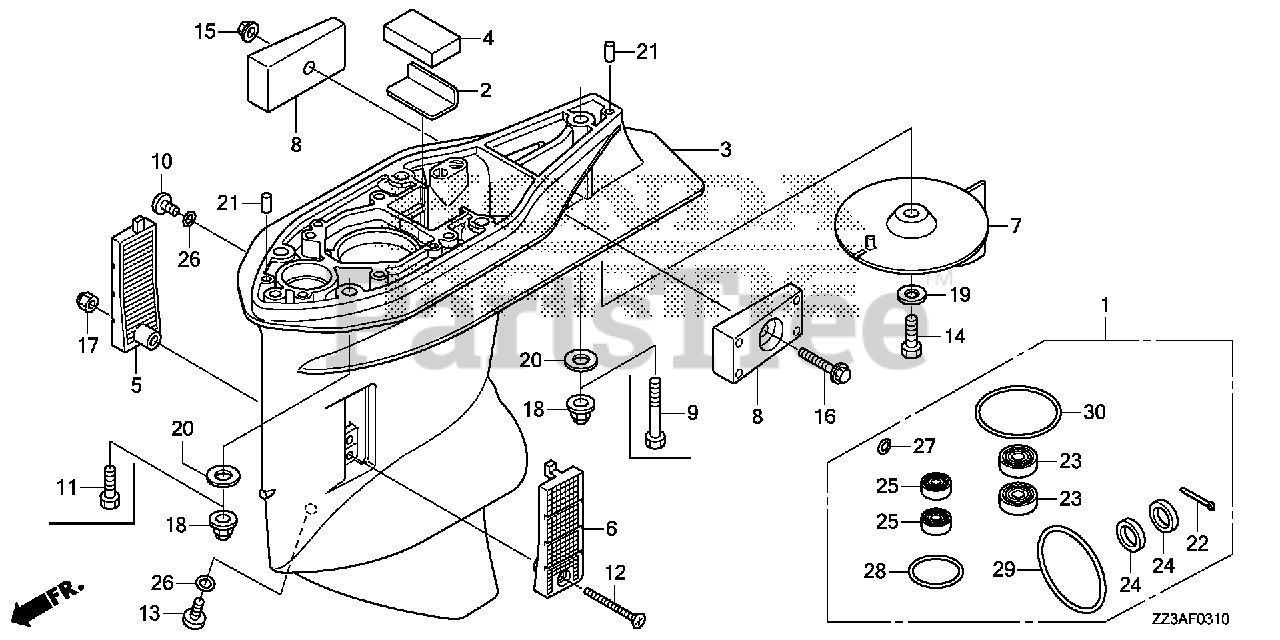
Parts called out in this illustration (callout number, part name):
1	CASE KIT, GEAR
2	PLATE, RUBBER SETTING
3	CASE, GEAR *NHB14M* (AQUA MARINE SILVER METALLIC)
4	GROMMET, GEAR CASE
5	SCREEN, R. WATER
6	SCREEN, L. WATER
7	TAB, TRIM *NHB14M* (AQUA MARINE SILVER METALLIC)
8	METAL, ANODE
10	BOLT, OIL CHECK
12	SCREW, FLAT (5X37)
13	BOLT, DRAIN PLUG
14	BOLT, HEX. (8X20)
15	NUT, SELF-LOCK (6MM)
16	BOLT, FLANGE (6X30)
17	NUT, SELF-LOCK (5MM)
18	NUT, SELF-LOCK (10MM)
19	WASHER, PLAIN (8MM)
20	WASHER, PLAIN (10MM)
21	PIN, DOWEL (6X10)
22	PIN, SPLIT (4.0)
23	SEAL, WATER (17X36X6)
24	SEAL, WATER (22X35X7)
25	SEAL, WATER (12X21X6)
26	O-RING (6.9X1.45)
27	O-RING (6.9X1.45)
28	O-RING (33.7X3.5)
29	O-RING (76.5X3)
30	O-RING (58.5X3.5)
